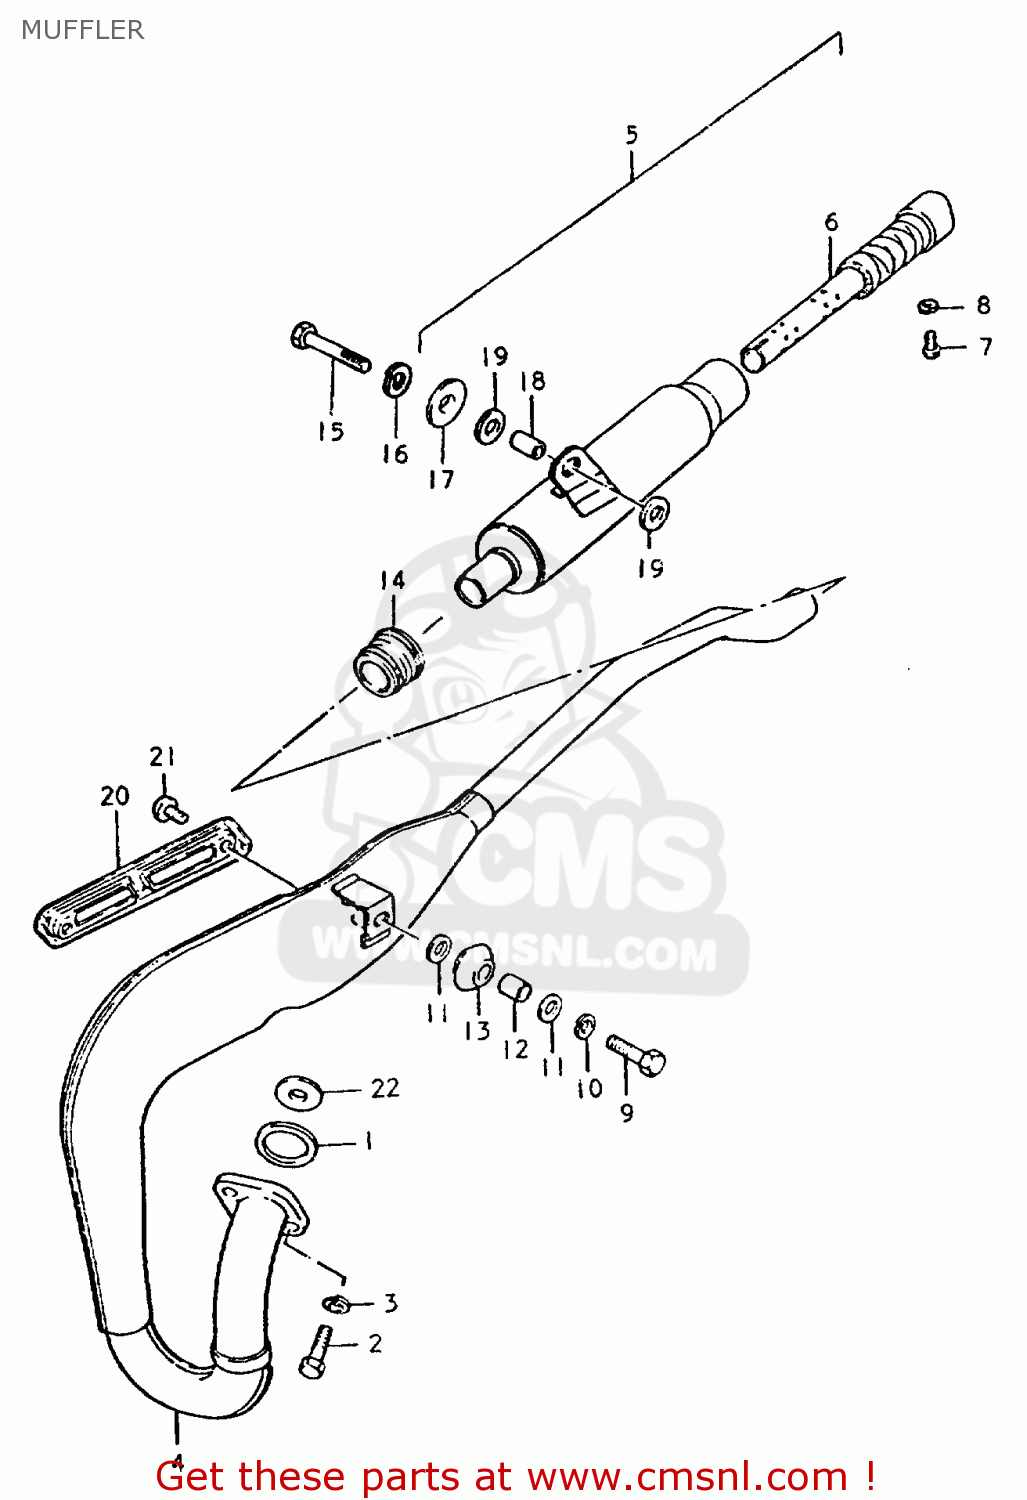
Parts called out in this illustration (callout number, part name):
1	GASKET,EXHAUST PIPE (NAS)
2	BOLT
3	LOCK WASHER
4	MUFFLER, 1ST
5	MUFFLER, 2ND
6	PIPE, BAFFLE
7	BOLT(5X8)
8	LOCK WASHER
9	BOLT (8X30)
10	LOCK WASHER
11	WASHER
12	SPACER (8X12X15)
13	DAMPER,MUFFLER,FR
14	CONNECTOR,MUFFLER
15	BOLT
16	LOCK WASHER
17	WASHER
18	SPACER (8.6X13.8X9)
19	CUSHION
20	COVER,MUFFLER
21	SCREW
22	PLATE, EXHAUST PIPE
